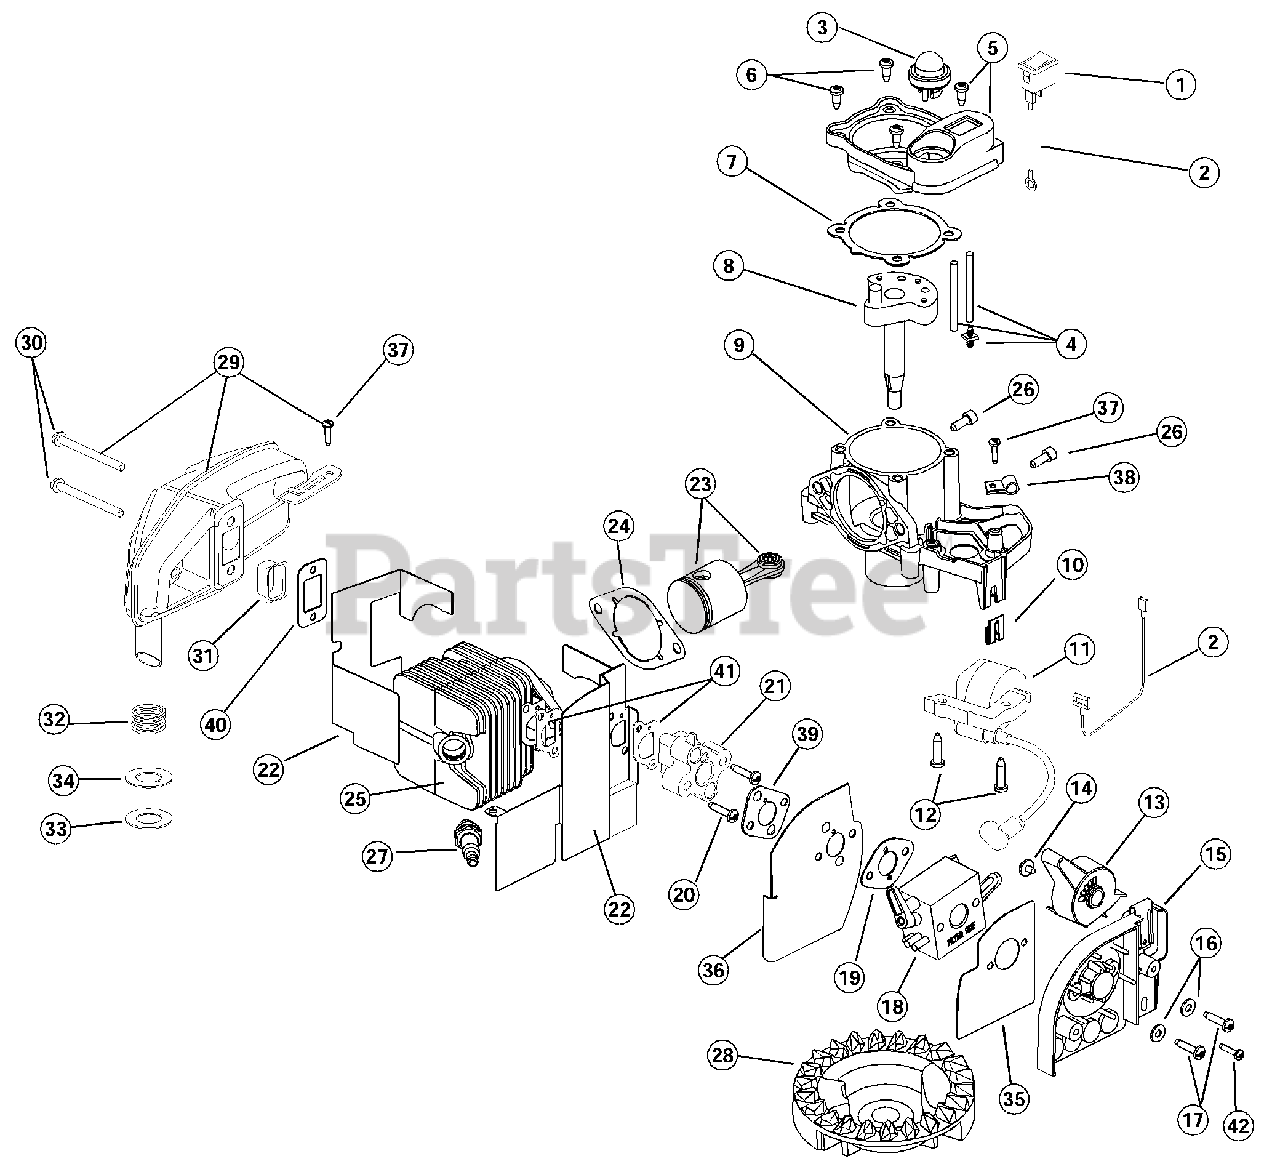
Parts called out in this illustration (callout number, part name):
1	On/Off Stop Control Switch with Wire
2	Wire Lead
3	Primer Bulb
4	Return Lines
5	Crankcase Plug
6	Crankcase Plug Screws
7	Crankcase Plug Gasket
8	Power Shaft Assembly
9	Crankcase Assembly
10	Tinnerman Nut
11	Module Assembly
12	Module Screw
13	Throttle Lever
15	Air Cleaner Base
17	Carburetor Mount Screw
18	Carburetor
19	Carburetor Gasket
20	Spacer Mounting Screw
21	Carburetor Spacer
22	Cylinder Baffle Assembly
23	Piston and Rod Assembly
24	Cylinder Gasket
25	Cylinder Assembly
26	Cylinder Bolt
27	Spark Plug
28	Flywheel
29	Muffler Assembly
30	Muffler Mounting Screw
31	Spark Arrestor Screen
32	Exhaust Tube Spring
33	Exhaust Tube Washer
34	Exhaust Tube Gasket
35	Air Filter Heat Shield
36	Carburetor Heat Shield
39	Heat Shield Gasket
40	Exhaust Gasket
41	Intake Gasket
